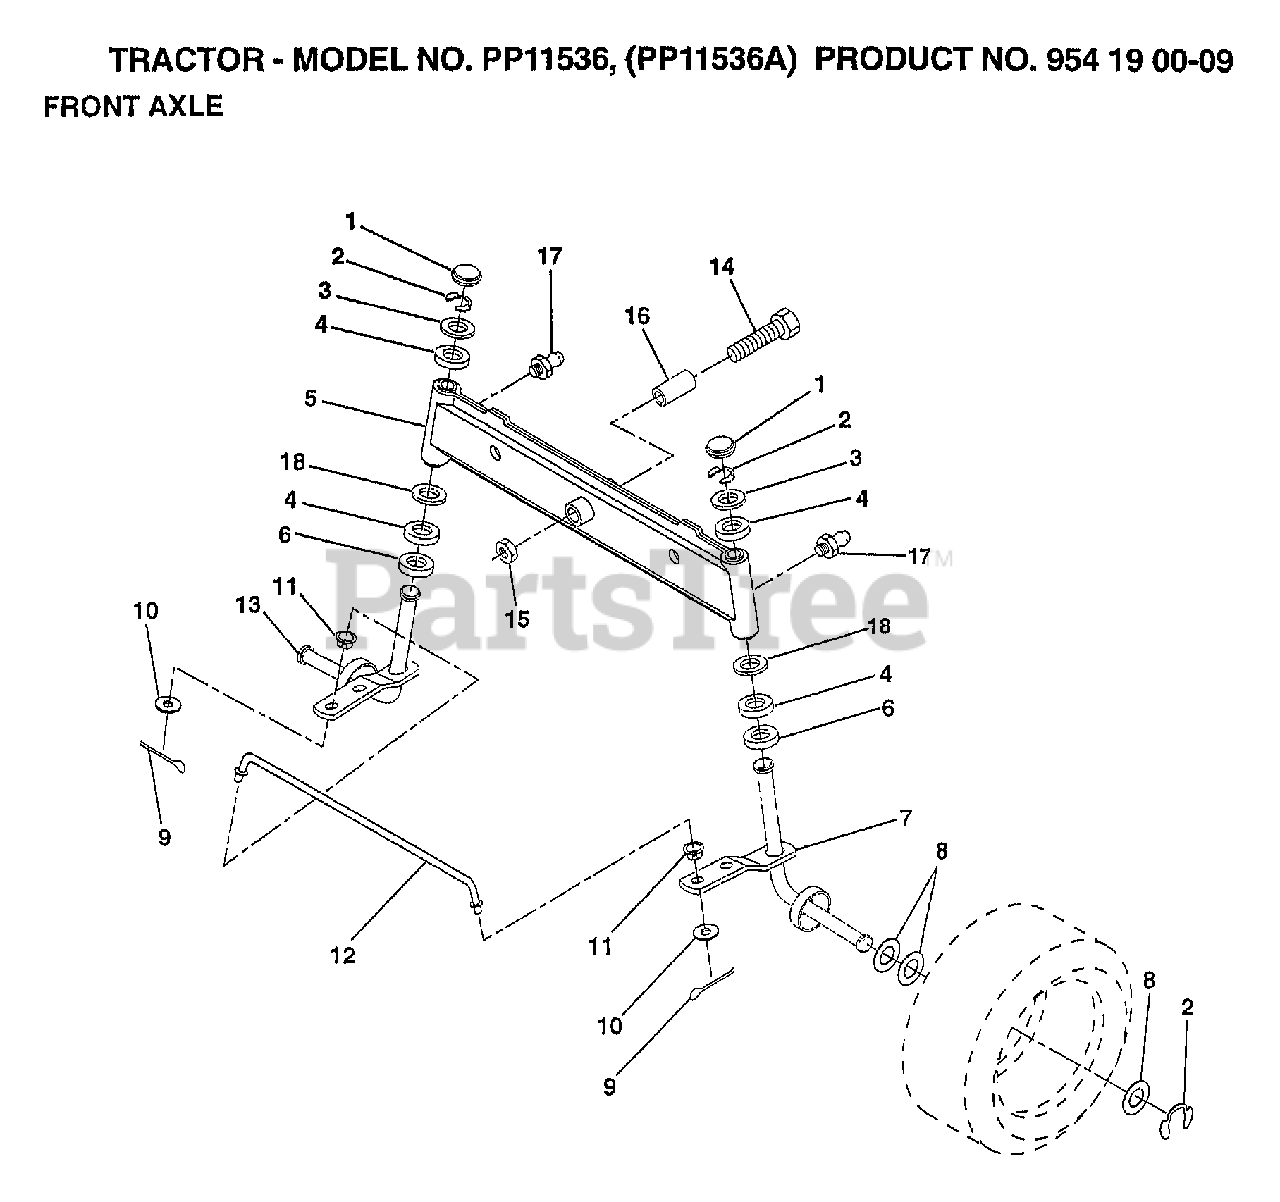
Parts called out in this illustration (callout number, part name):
1	CAP
2	RING
3	WASHER
4	COL. SRTG. BEAR.
5	AXLE ASM FRONT
6	WASHER .T
7	SPINDLE ASM RH
8	WASHER
9	COTTER PIN
10	WASHER
11	BUSHING.DRAGLINK
12	TIE ROD
13	SPINDLE ASM LH
14	BOLT HEX 5/8-11
15	"NUT-LOC,FLANGE LT"
16	BEARING
17	ZERK M
18	WASHER
